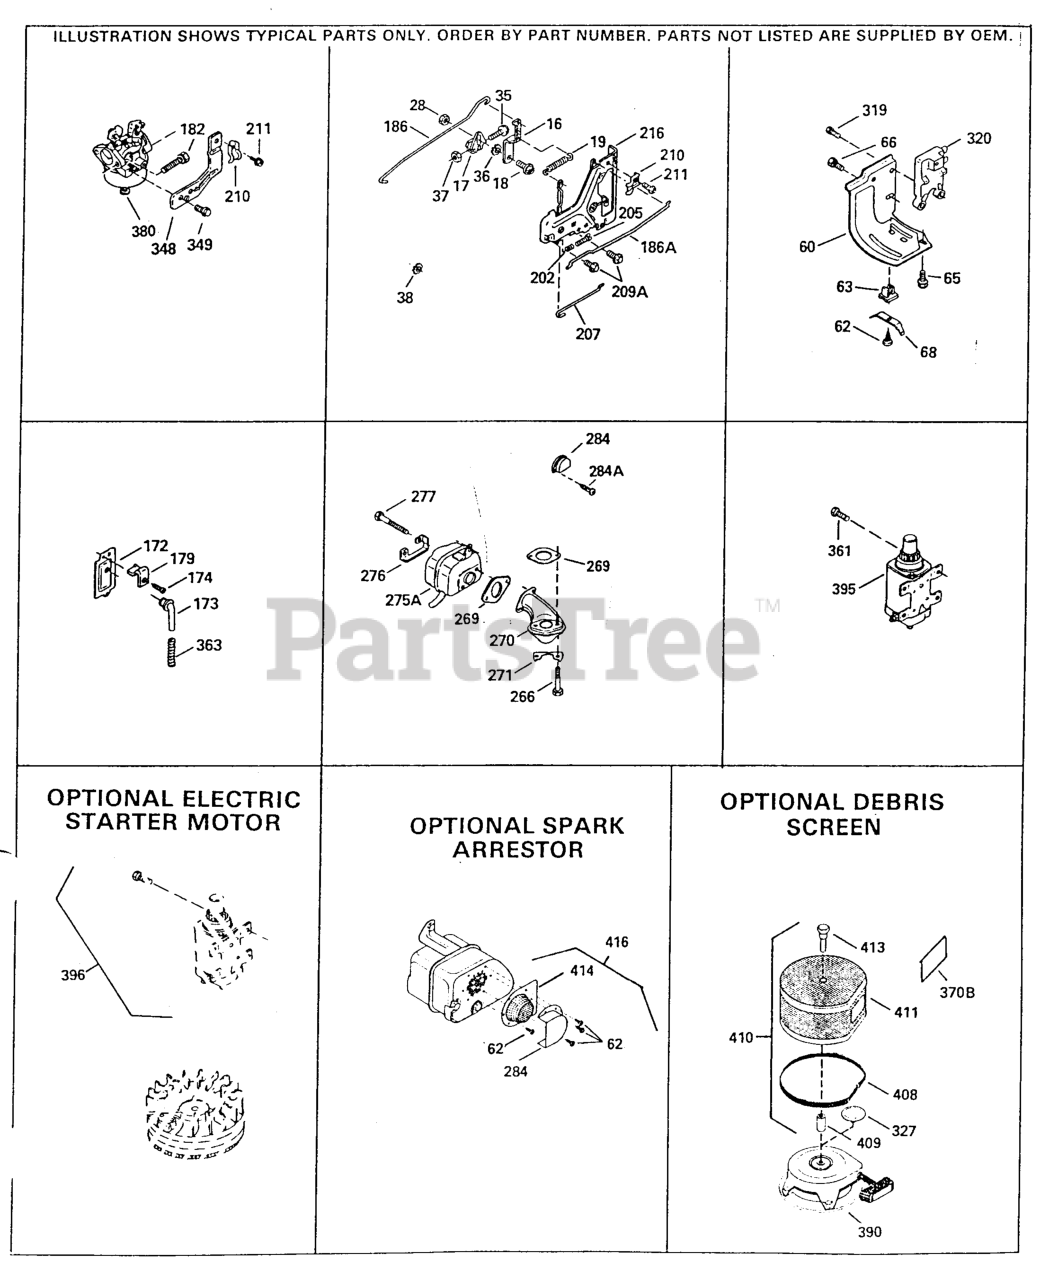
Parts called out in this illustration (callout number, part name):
16	GOV LEVER
18	SCREW
19	EXT SPRING
38	RET RING
60	EXTENSION
172	VALVE COVER
186	GOV LINK
186A	CONTROL LINK
320	REGULATOR
380	CARBURETOR
395	STARTER
